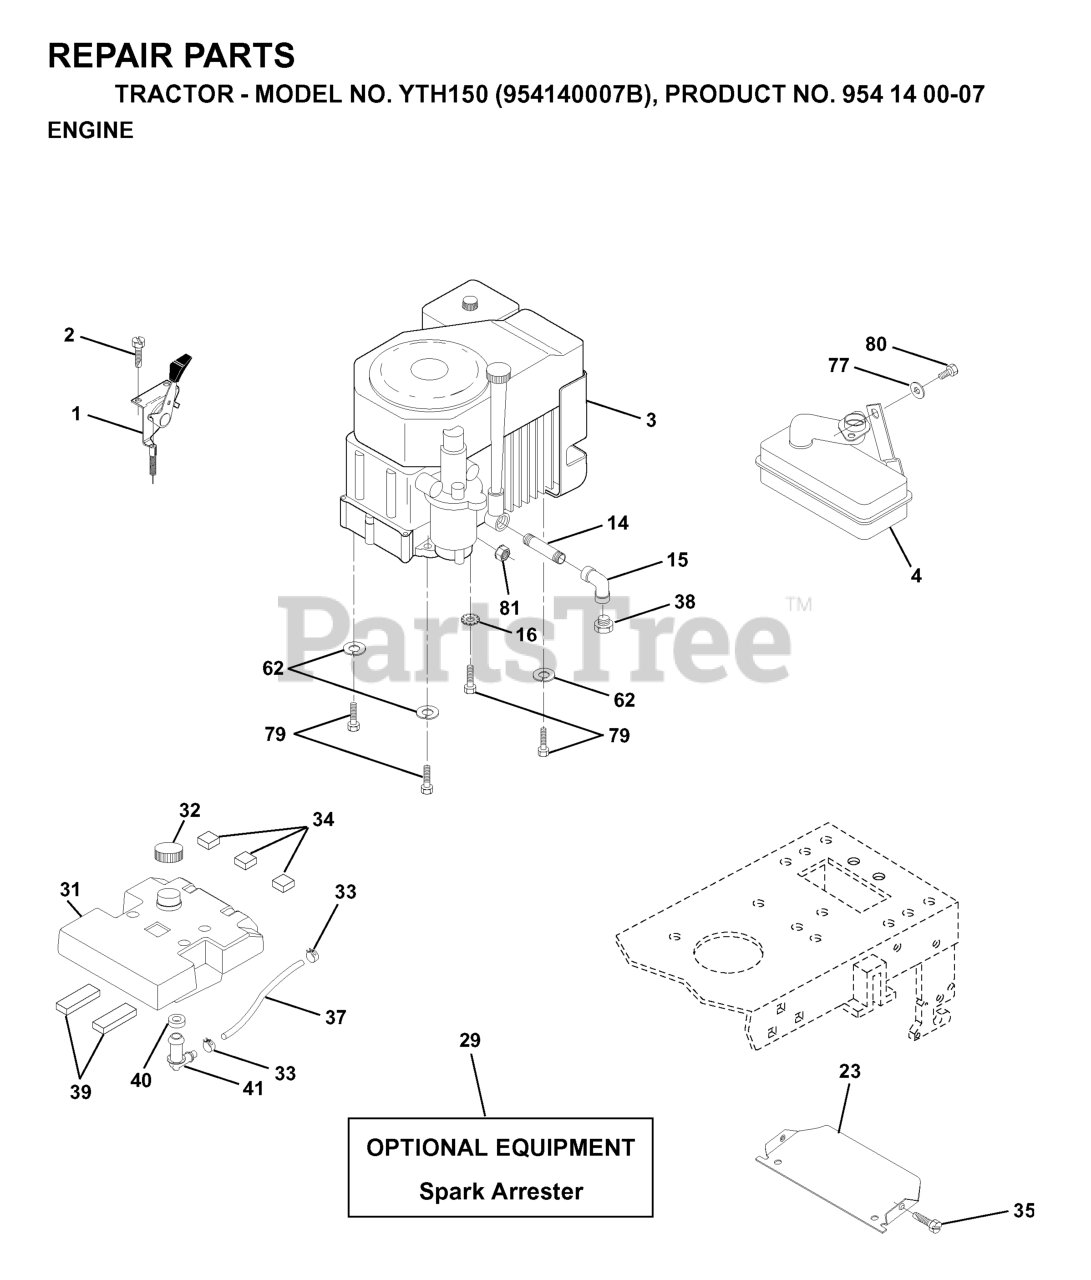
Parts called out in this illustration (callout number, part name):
2	SCREW LT
4	MUFFLER LT 12.5
14	Std. Pipe Nipple 3/8 - 18 NPT x 3 1/2
15	ELBOW
16	WASHER EXT TOOTH LOCK 5/16
23	SHIELD HEAT
29	KIT.SPARK ARRESTOR 794945 B&S
31	TANK.FUEL(3.5.GAL)
32	FUEL CAP
33	HOSE CLAMP
34	PAD-SPACER LT
35	SCREW.THDROL.5/16-18X3/4.TTY
37	HOSE T
39	PAD IDLER TI
40	BUSHING OUTLET T
41	STEM FUEL TANK
62	WASHER.LOCK.HVY.HLCL.SPR.5/16
77	WASHER
79	BOLT, HEX
80	Bolt, Hex Head, Fin. 5/16-18 x 1/2
81	NUT FLANGE 1/4-20 STARTER NUT
